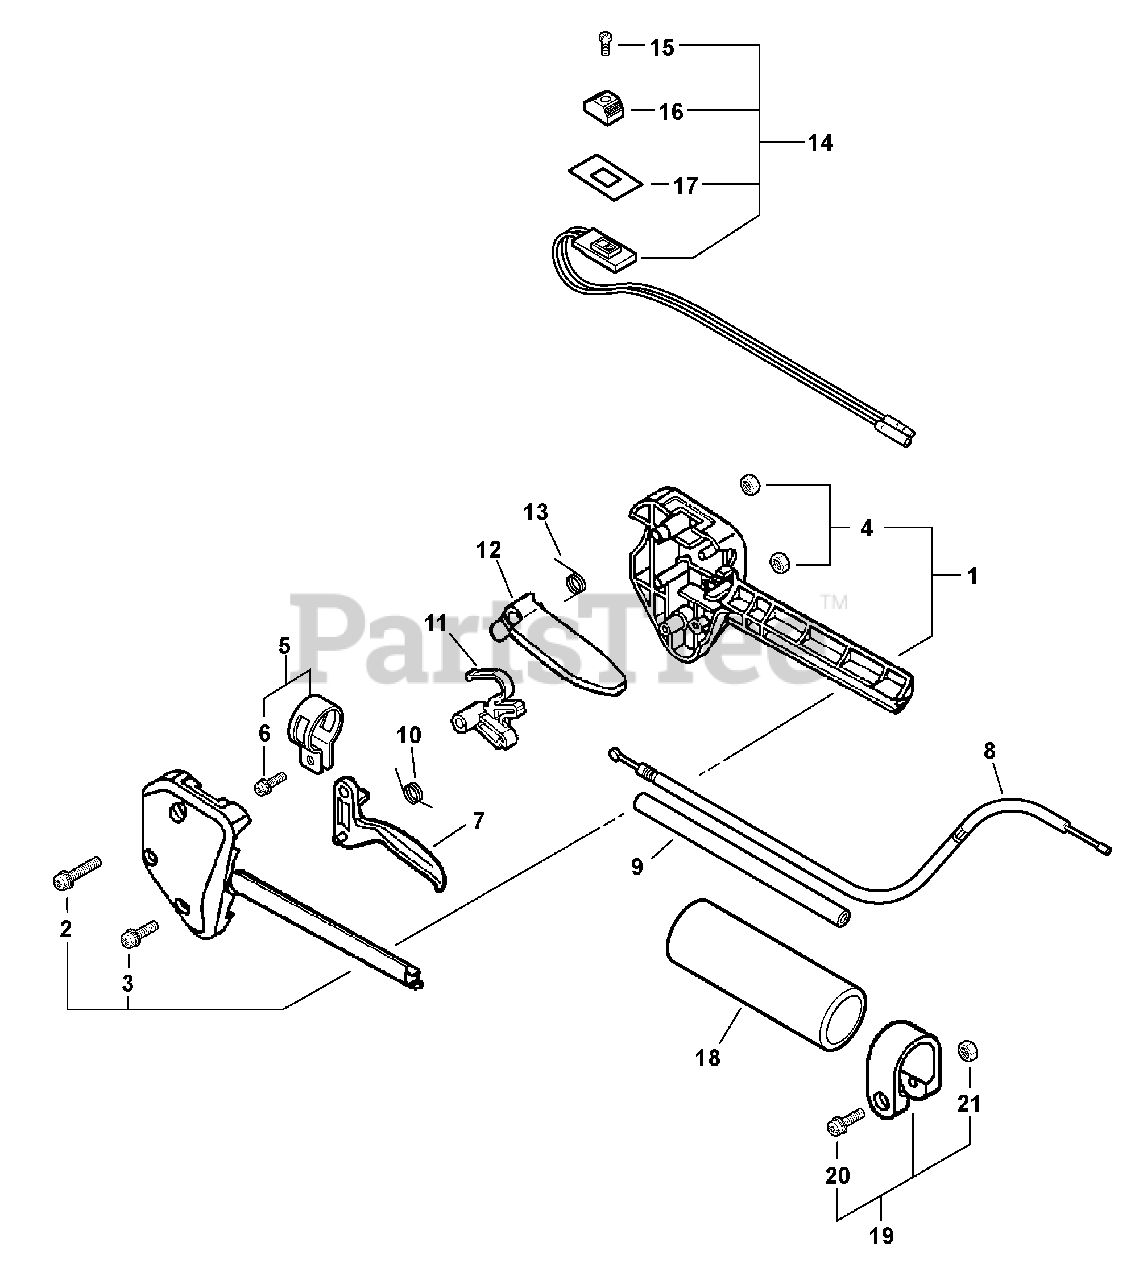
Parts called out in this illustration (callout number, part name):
1	Control Handle Kit
2	Screw 5x35
3	Screw 5x25
5	Band Asy
6	Screw 5x14
7	Trigger,Throttle
8	Cable, Throttle
9	Tube, Vinyl
10	Spring, Throttle Return
11	Lockout, Throttle Trigger
12	Lever, Throttle Trigger Lockout
13	Spring, Throttle Lockout
14	Ignition Switch Asy
15	Screw 3x10
16	Knob, Switch
17	Cover, Switch
18	Grip, Handle
19	Clamp Kit
20	Screw 5x28
